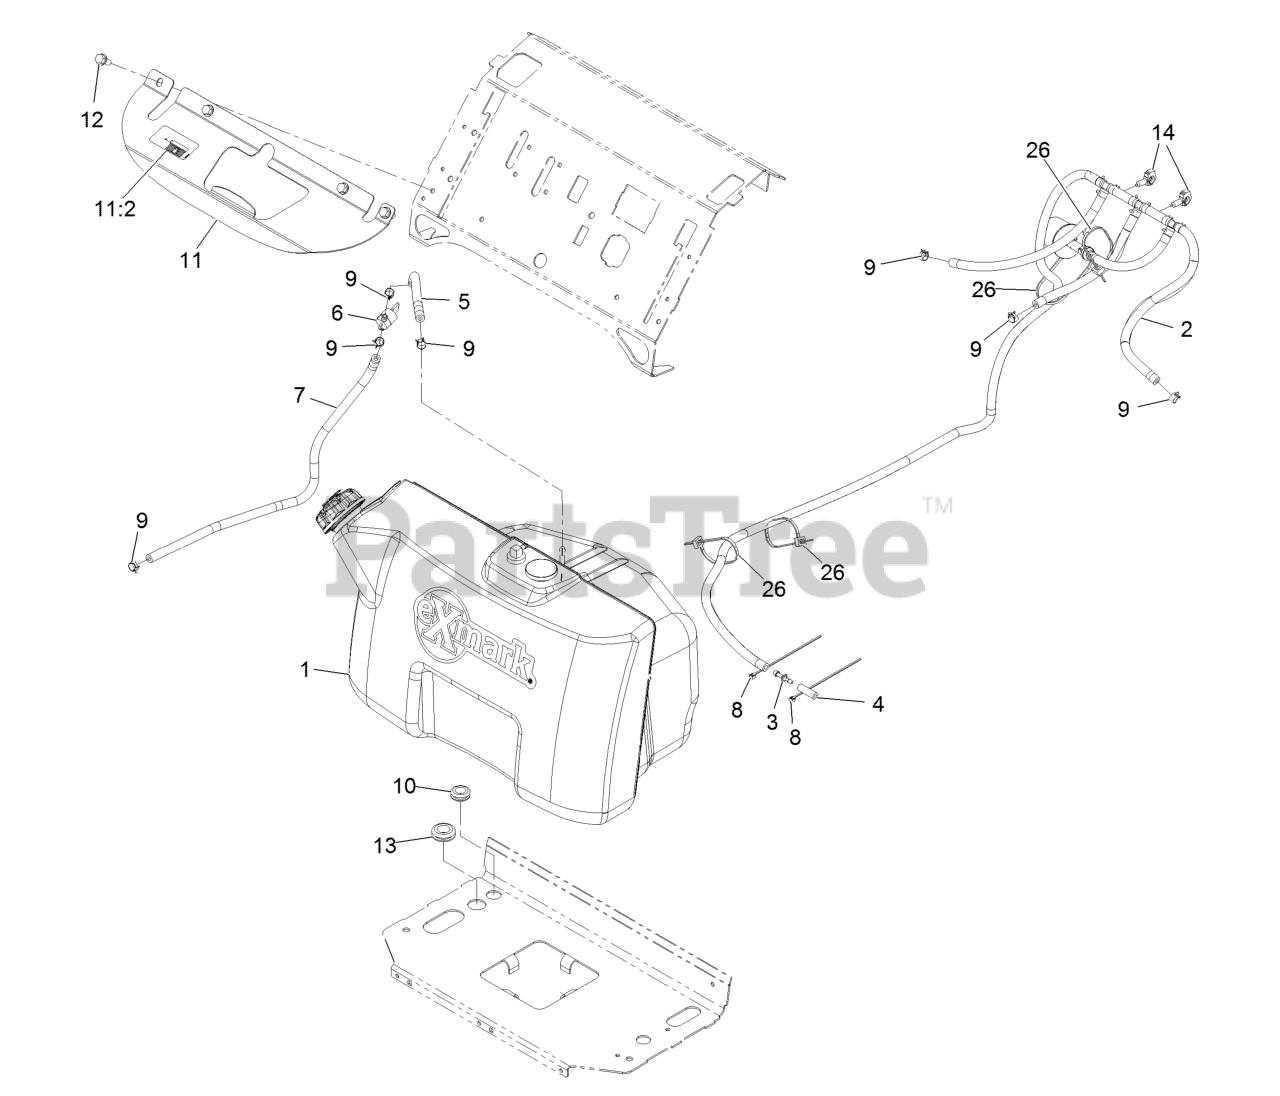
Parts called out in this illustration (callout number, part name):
2	VENT ASM
3	FITTING-STRAIGHT
4	HOSE-FUEL
5	HOSE-FUEL
6	VALVE-FUEL
7	HOSE-FUEL
8	TIE-CABLE
9	CLAMP-HOSE
10	GROMMET
11	BRACKET-TANK
11:2	DECAL-FILL, FUEL
12	Screw-HWH 5/16-18 X 3/4 Tf
13	GROMMET
14	CLIP-HARNESS
26	TIE-CABLE
